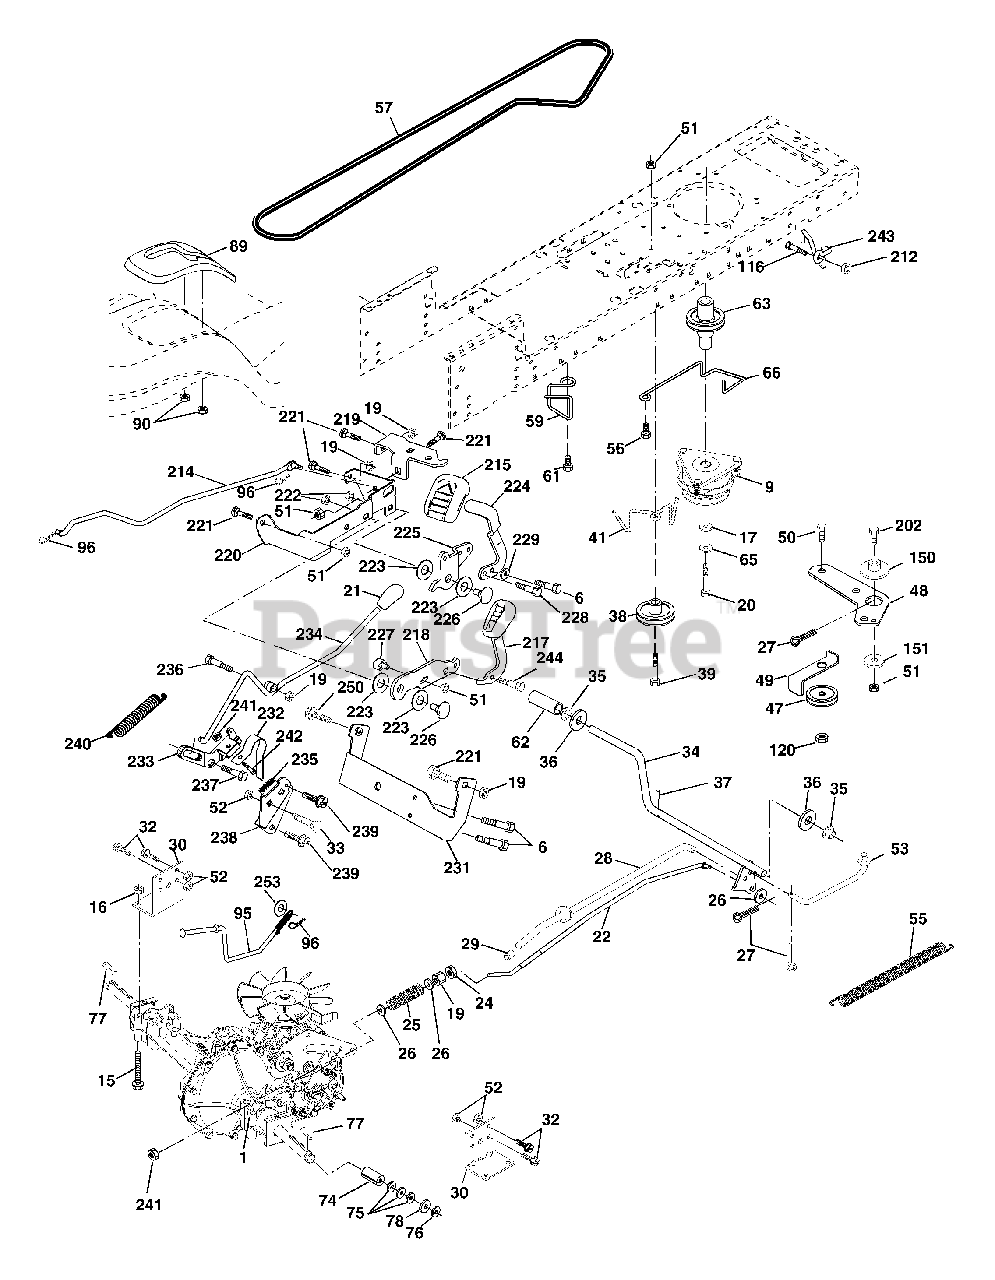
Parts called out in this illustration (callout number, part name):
6	Screw 5/16-18 x 3/4
9	Clutch Elec
15	Bolt Hex Flghd 5/16-18 Gr. 5
16	Nut Lock Hex W/Ins. 5/16-18 Unc
17	Washer 1-1/2 OD x 15/32 ID x .250
19	Nut Lock Hex W/Wsh 3/8-16 Unc
20	Bolt Hex 7/16-20 x 4 x Gr. 5-1.5
21	Knob Custom Control Cruise
22	Rod, Brake
24	Nut, Hex Jam 3/8-16 Unc
25	Spring, Brake Rod
26	Washer
27	Pin Cotter 1/8 x 3/4 CAD.
28	Rod, Parking Brake
29	Cap, Brake, Park
30	Bracket, Transaxle
32	Bolt Hex Hd 5/16-18 Unc x 3/4
33	Bolt Rdhd Sqnk 5/16-18 Unc x 3/4
34	Shaft, Foot Pedal
35	Bearing, Nylon
36	Washer
37	Pin, Roll
38	Pulley, Composite, Flat
39	Bolt Fin Hex 3/8-16 Unc x 3
41	Keeper, Belt Idler Flat
47	Pulley, Idler, V-Groove
48	Bellcrank Clutch Grnd Drw Stl
49	Retainer, Belt
50	Bolt
51	Nut Crownlock 3/8-16 UNC
52	Nut, Crownlock 5/16-18 Unc
53	Link, Clutch
55	Spring, Return, Clutch
56	Screw 3/8-16 x 1.0
57	V-Belt, Ground Drive
59	Keeper, Center Span
61	Screw 3/8-16 x .875
62	Cover, Pedal
63	Pulley, Engine
65	Washer
66	Keeper Belt Engine
74	Spacer, Axle
75	Washer 25/32 x 1-1/4 x 16 Ga.
76	E-Ring
77	Key, Square
78	Washer 25/32 x 1-5/8 x 16 Ga.
89	Console, Shift
90	Nut Self-Thd Wsh-hd 1/4 Zinc
95	Rod Bypass
96	Retainer Spring 1" Zinc/Cad
116	Bolt RDHD SQNK 3/8-16 Unc x 1
120	Nut Lock Flg 3/8-16 Unc
150	Spacer Retainer
151	Washer 13/32 x 2 x 10 Ga.
202	Bolt Carr Sh 3/8-16 x 1-1/2 Gr. 5
212	Nut Hex Flange Lock
214	Link Transaxle
215	Cover Pedal Forward
217	Pedal Reverse
218	Arm Control Pedal Reverse
219	Bracket Frest Pdl Ctrl. Hyd
220	Bracket Mtg. Pedal Control
221	Bolt Rdhd Sqnk 3/8-16 Unc x 3/4
222	Nut Crownlock 7/16-14 Unc
223	Washer Nylon 11/16 ID x .060
224	Pedal Forward
225	Arm Control Pedal Forward
226	Bolt Pivot Spacer
227	Cam Reverse Pedal LT
228	Bolt Shoulder 5/16-18
229	Washer Serrated 5/16 x .75
231	Strap Torque
232	Actuator Cruise Disengage
233	Pawl Control Cruise
234	Lever Control Cruise
235	Sector Control Cruise
236	Bolt Shoulder 3/8-16 Unc 1/44
237	Bolt Shoulder 5/16-18
238	Arm Mtg. Cruise Sector
239	Screw Thdrol 5/16 x 1/2
240	Spring Return Cruise Control
241	Nut Centerlock 1/4-20 Unc
242	Bolt Fin Hex 1/4-20 Unc x .75
243	Bracket Anti-Rotation CVX
244	Screw 5/16-18 x 5/8
250	Screw 3/8-16 x .75
253	Washer .3125 x .615 x 16 Ga.
